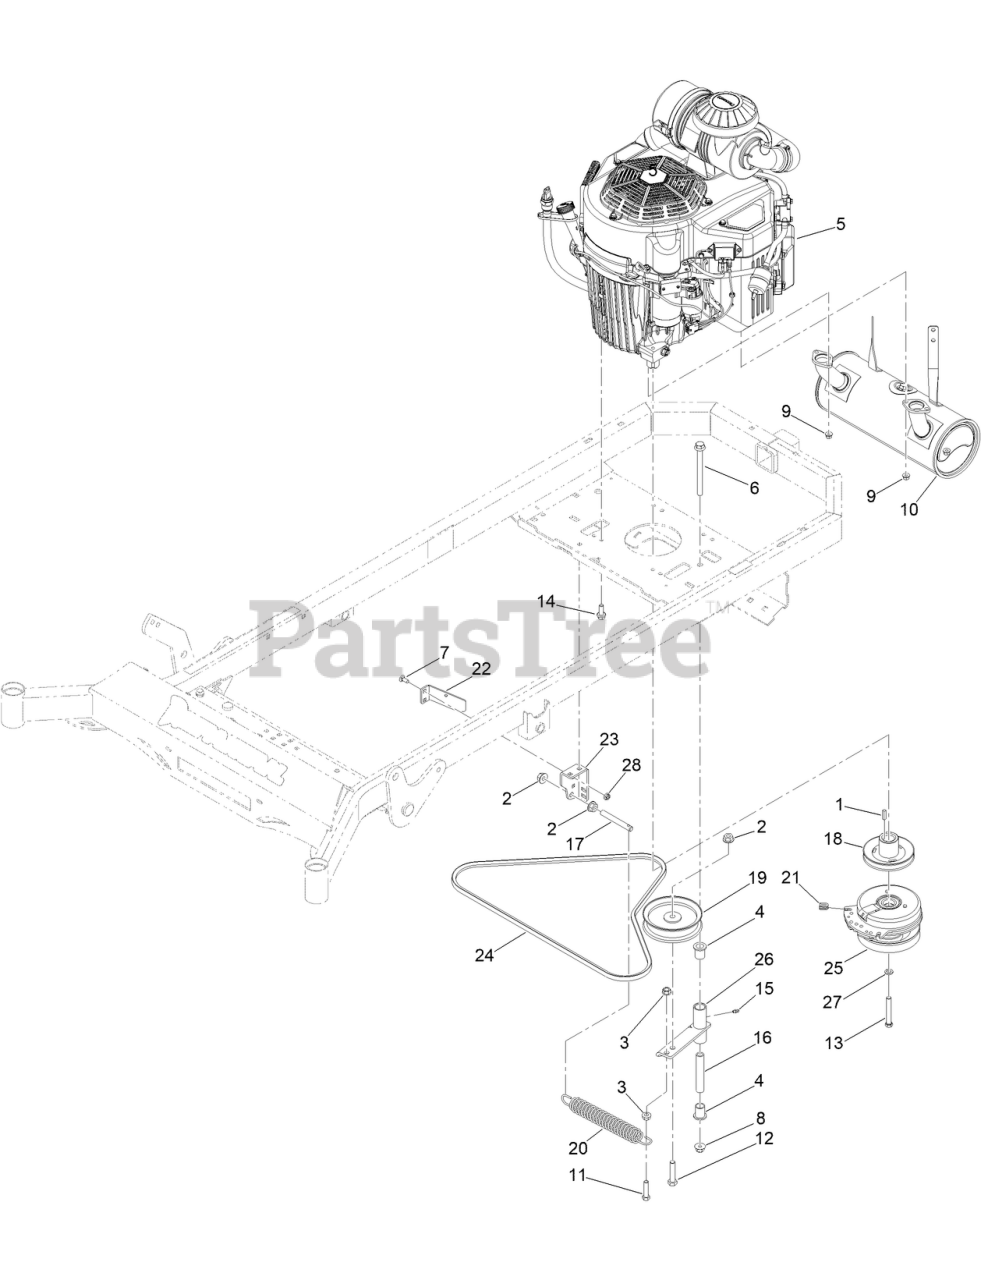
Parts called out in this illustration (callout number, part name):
2	NUT-HHF
3	NUT-HF
4	3/4IN ID X15/16IN OD X 1-1/8IN FLNG BUSH
5	FXT100V (1000 CARBURETED) ENGN
6	1/2-13 X 5-1/2 HEX FLANGE BOLT GR 8 ZY
7	BOLT-CARR
8	NUT-LOCK
9	NUT-HF
10	MUFFLER W/ ARRESTER-6INOD-1.5INTP
11	SCREW-HH
12	SCREW-HH
13	7/16-20 X 3 HEX C/S GR 8 ZC YELLOW
14	3/8-16 X 1-1/8 IND HWH W/SERR TRI LOB ZY
15	1/4IN DRIVE TYPE GREASE FITTING YZ
16	MWR INNER IDLER SPACER
17	MWR PUMP IDLER SPRING TENSIONER
18	MWR HYDRAULIC PUMP DRIVE PULLEYA BELT
19	5-3/4IN IDLER PULLEY 7/16IN SPACER ASSY
20	MWR DECK SPRING
21	MWR CLUTCH ROTATION STOP BRKT SLEEVE
22	MWR CLUTCH ANTI ROTATION BRKT PAINTED
23	MWR PUMP IDLER TENSIONING BRKTPAINTED
24	MWR PUMP BELT RT A X 68.25IN EFF LNGTH
25	WARNER PTO CLUTCH
26	MWR PUMP IDLER ASSY PAINTED
27	WASHER-LOCK
